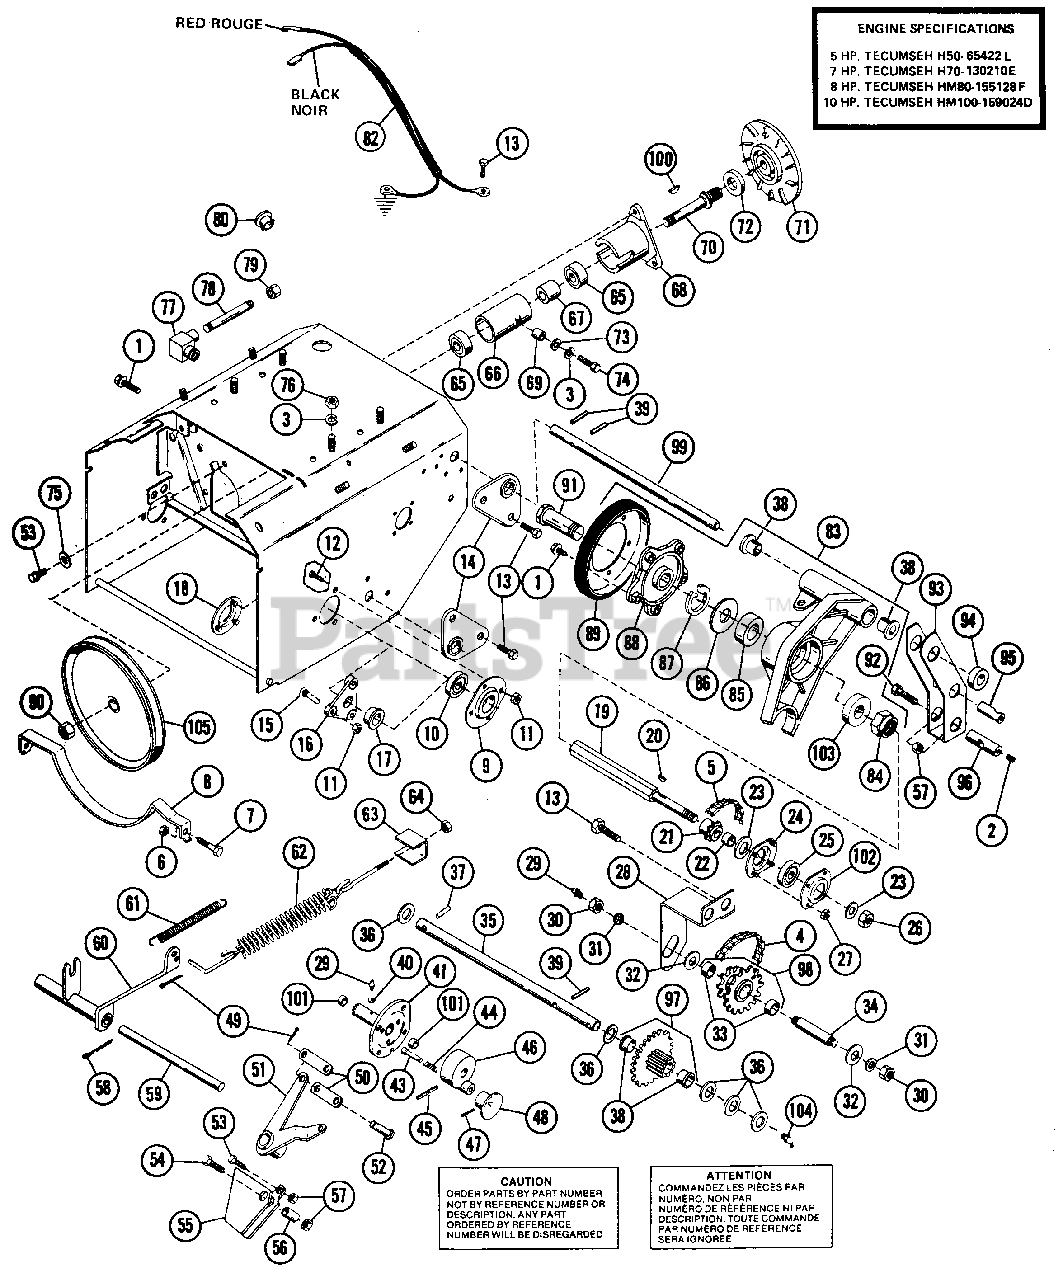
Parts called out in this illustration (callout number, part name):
1	BLT-SERHFWH .31-18X.50 PL
2	SCR-SET .32-18X.38 SKHCUPNL OH
3	WSHR-LK .312X.097 PL HVY
4	NOT USED ON THIS MODEL
5	CHAIN
6	NUT-LK-CTR .250-20 PL
7	BLT-HEX .25-20X.50 PL GR2
8	BELT RETAINER
9	BEARING FLANGE
10	BRG-BALL .876 X 1.750 X .50
11	NUT-LK-FLG .250-20 PL
12	NOT USED ON THIS MODEL
13	BLT-SERHFWH .25-20X.50 PL
14	SUPPORT, SHAFT
15	NOT USED ON THIS MODEL
16	NOT USED ON THIS MODEL
17	NOT USED ON THIS MODEL
18	BEARING FLANGE
19	HEX SHAFT
20	KEY-WDRF .125X.625X.250 SAE5
21	9 TOOTH SPROCKET
22	ROLLER
23	WSHR-FL-STL .505X1.000X.062
24	BEARING FLANGE
25	BRG-BALL .500X1.38X.437
26	NUT-LK-CTR .50-20 PL
27	NUT-LK DUAL FACE 10-24 PL
28	CLUTCH STOP
29	SPIN DRIVE ZERK FITTING
30	NOT USED ON THIS MODEL
31	NOT USED ON THIS MODEL
32	NOT USED ON THIS MODEL
33	NOT USED ON THIS MODEL
34	NOT USED ON THIS MODEL
35	PINION SHAFT
36	WSHR-FL-STL .630X1.005X.062 PL
37	PIN-ROLL .125X1.00
38	BSHG-FLG .625X.750X.500X.875BR
39	PIN-ROLL .156X1.00
40	WSHR-LK .250X.047 LT PL
41	L H AXLE ASSEMBLY
42	BSHG-SLV .562X.625X.625 BRZ
43	PIN
44	SG-COMP .028X.34X1.062 WLD75
45	PIN-GRV .250X1.75 TP C
46	LOCKOUT HUB
47	PIN-ROLL .093X1.00
48	KNOB
49	PIN-COTR .09X.75 PL
50	SHIFT LINK
51	LEVER - SHIFT ARM
52	CLEVIS PIN
53	BLT-HEX .31-18X.50 PL GR2
54	BLT-HEX .31-18X3.00 PL GR2
55	BRACKET SHIFT LEVER
56	SPACER .5 X .33 X 2.4
57	NUT-LK .312-18 GR A PL
58	PIN-COTR .09X1.0 PL
59	ROD, FORK PIVOT
60	FORK, CLUTCH
61	SG-TENS .080X.73X3.06 WLD 20
62	SPRING ASSEMBLY
63	ADAPTER SPACER
64	NUT-LK-NYL.312-18 PL
65	BRG-BALL .625X1.375X.44
66	SPINDLE HOUSING
67	BEARING SPACER
68	DRIVE SPINDLE HOUSING
70	SPINDLE
71	DRIVE PLATE
72	DRIVE DISC SPACER 1.3X.76X.19
73	WSHR-FL-STL.344X.688X.065PL
74	BLT-HEX .31-18X1.00 PL GR 2
75	WSHR-LK-INT .313X.030 PL
76	NUT-HEX .312-18
77	NOT USED ON THIS MODEL
78	NOT USED ON THIS MODEL
79	NOT USED ON THIS MODEL
80	BUTTON PLUG 1.0
81	SNAP BUSHING-.437
82	SHORTING WIRE
83	FRICTION WHEEL ASSEMBLY
84	NUT-LK-NYL .875-14
85	BRG-BALL .876 X 1.750 X .50
86	WSHR-FL-STL .880X1.250X.062
87	RG-RTNG-INT 1.750X.062
88	DISC HUB
89	FRICTION DISC
90	NUT-LK-NYL.625-18 PL
91	SPINDLE HUB
92	BLT-HEX .31-18X.75 PL GR2
93	CLUTCH ENGAGEMENT YOKE
94	SPACER 1.00 X .64 X .38
95	ADAPTER
96	ROD ADAPTER
97	PINION AND SPROCKET ASSY.
98	NOT USED ON THIS MODEL
99	CARRIER SHAFT
100	KEY-WDRF .125X.500X.203 SAE 3
101	BSHG-SLV .562X.625X.625 BRZ
102	BEARING FLANGE
103	BSHG-SLV .882X1.250X.531
104	HYDRAULIC DRIVE FITTING
105	PLY-V 8.00 X 1.0 W/KEY CLARK
